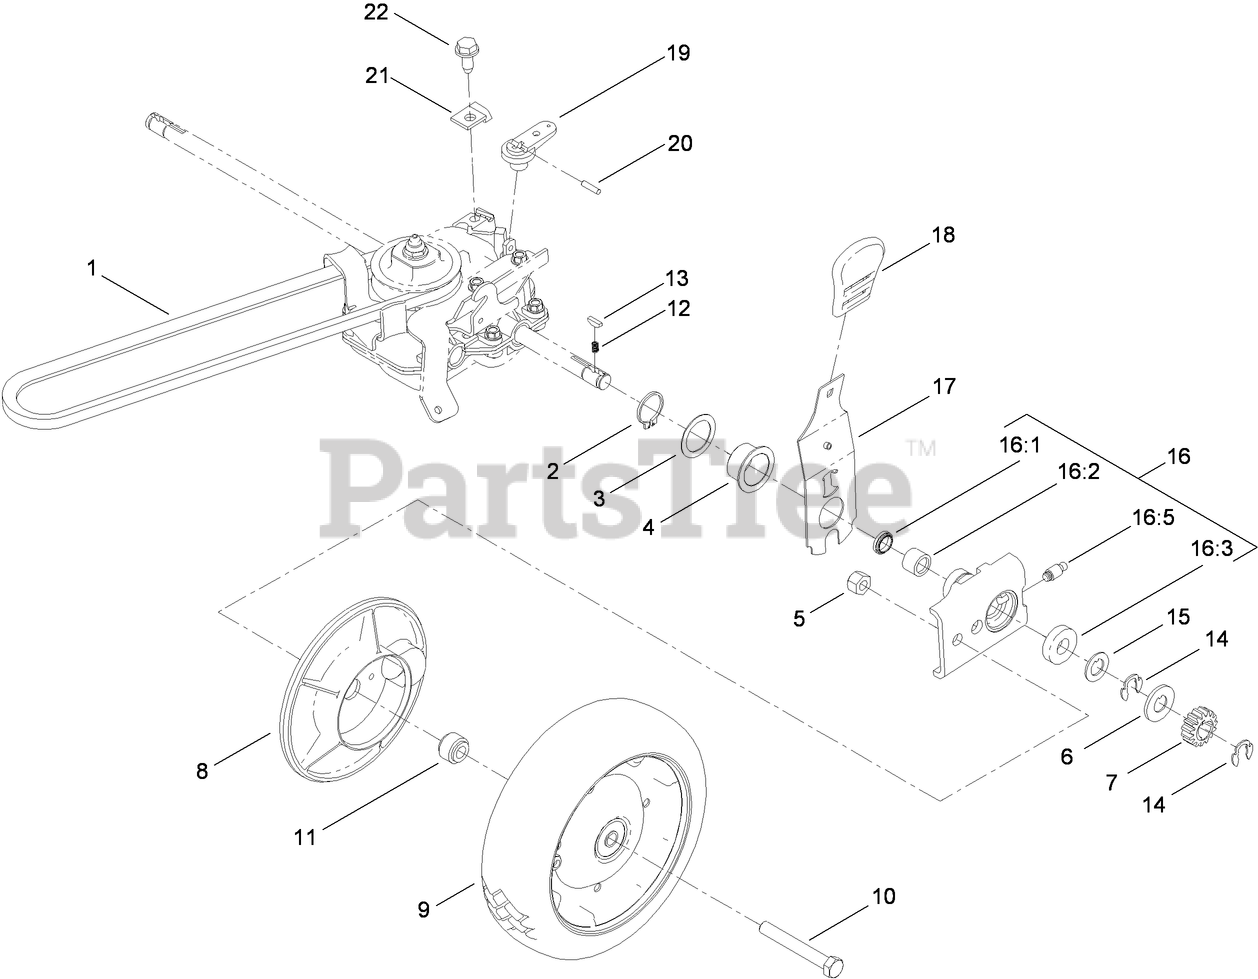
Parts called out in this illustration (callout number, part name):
1	V-BELT
2	RING-RETAINING
3	WASHER
4	BUSHING-FLANGE
5	NUT-LOCK, CONE
6	WASHER-THRUST, OUTER
7	GEAR-PINION
8	COVER-WHEEL
9	WHEEL AND TIRE ASM
10	SCREW-HH
11	SPACER-COVER, WHEEL
12	SPRING-COMPRESSION
14	RING-RETAINING
15	WASHER-THRUST, OUTER
16	PIVOT ARM ASM
16:1	SEAL-OIL
16:2	BEARING-CAGED NEEDLE ROLLER
16:3	BEARING-WHEEL
17	REAR SPRING ARM ASM
18	KNOB-HOC
19	LEVER-SHIFT
20	PIN-COIL
21	CLAMP-CABLE
22	SCREW-HWHTF
